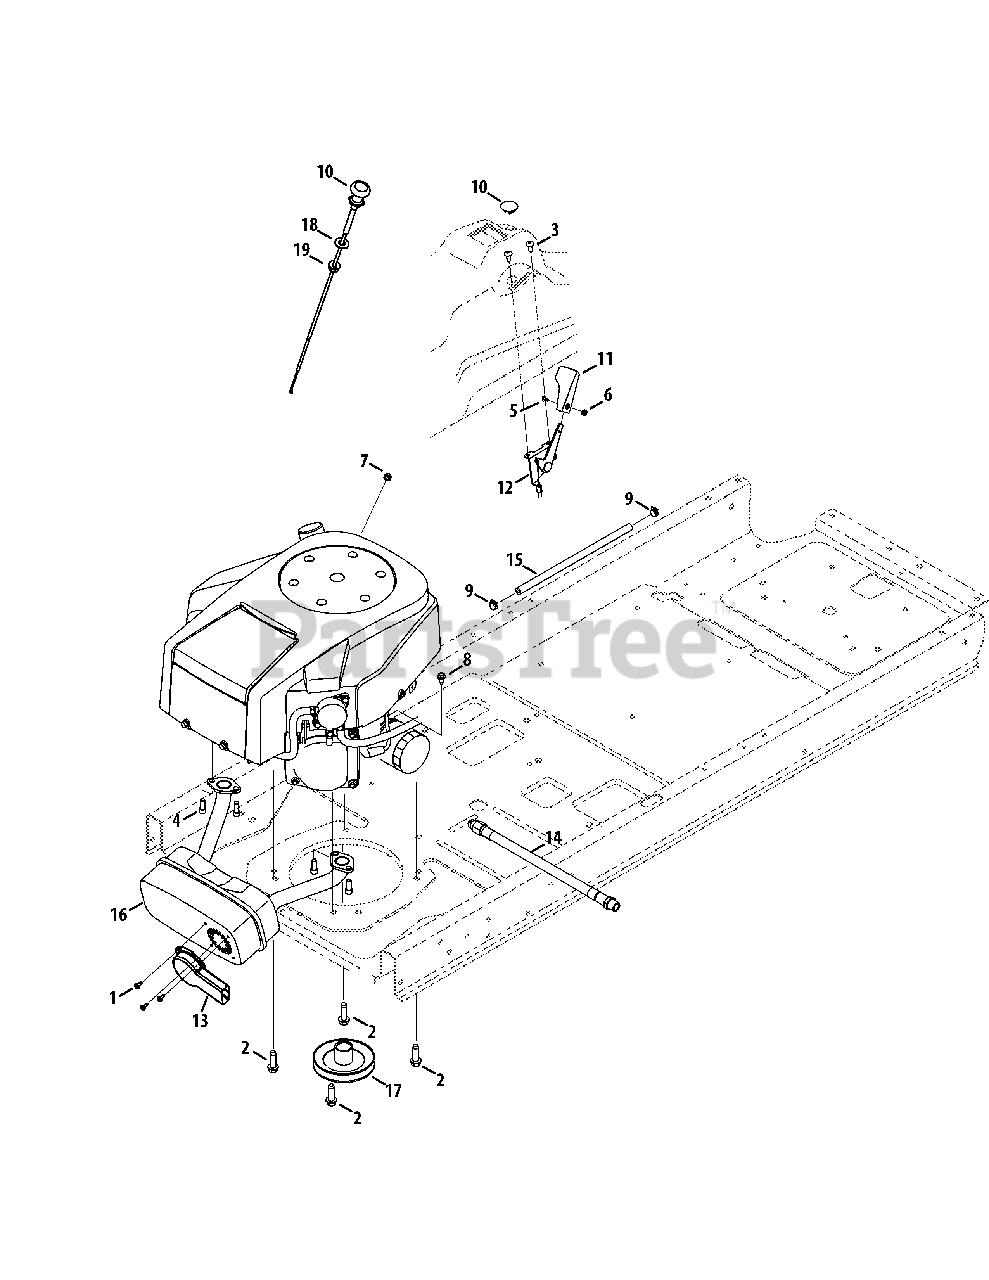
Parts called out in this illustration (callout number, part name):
1	Hex Washer Screw, #8-18 x .500
2	Hex Washer Screw, 3/8-16 x 1.00
3	Screw, 1/4-20 x .50
4	Socket Head Screw, 5/16-18 x .750
5	Screw, #8-32 x .375
6	Hex Nut, #8-32
7	Flange Lock Nut, 1/4-20
8	Hex Washer Screw, 1/4-20 x .625
9	Hose Clamp, .490 Dia.
10	Choke Plug
11	Throttle Control Knob
12	Throttle/Choke Control Cable
13	Muffler Deflector Long
14	Oil Drain Hose
15	Fuel Hose, 1/4
16	Twin Muffler
17	Engine Pulley
18	Flat Washer, .406 x .875 x .059
19	Flange Lock Nut, 3/8-16
